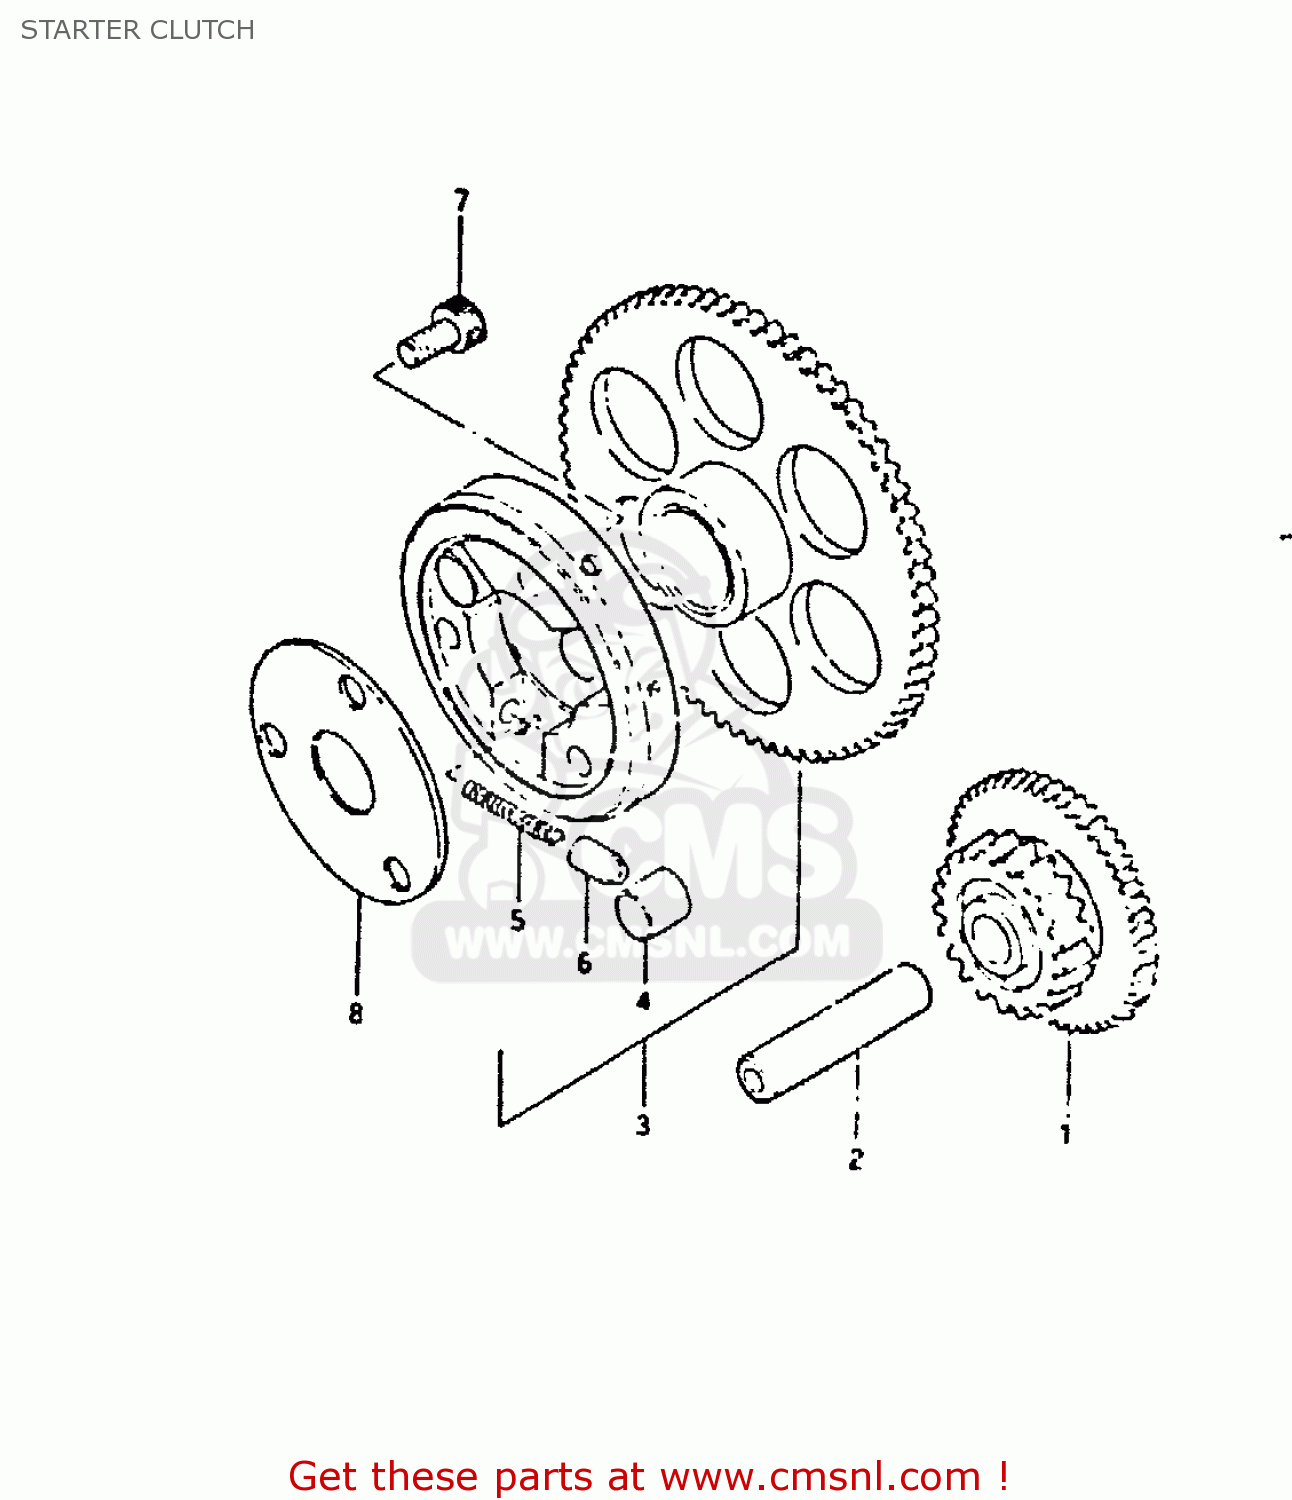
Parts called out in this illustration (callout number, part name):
1	GEAR,STARTER IDLE
2	PIN(7.4X13X56)
3	CLUTCH SET,STARTER
4	ROLLER(15X13)
5	SPRING
6	PIECE,PUSH
7	BOLT
8	SHIM,STARTER CLUTCH HUB
